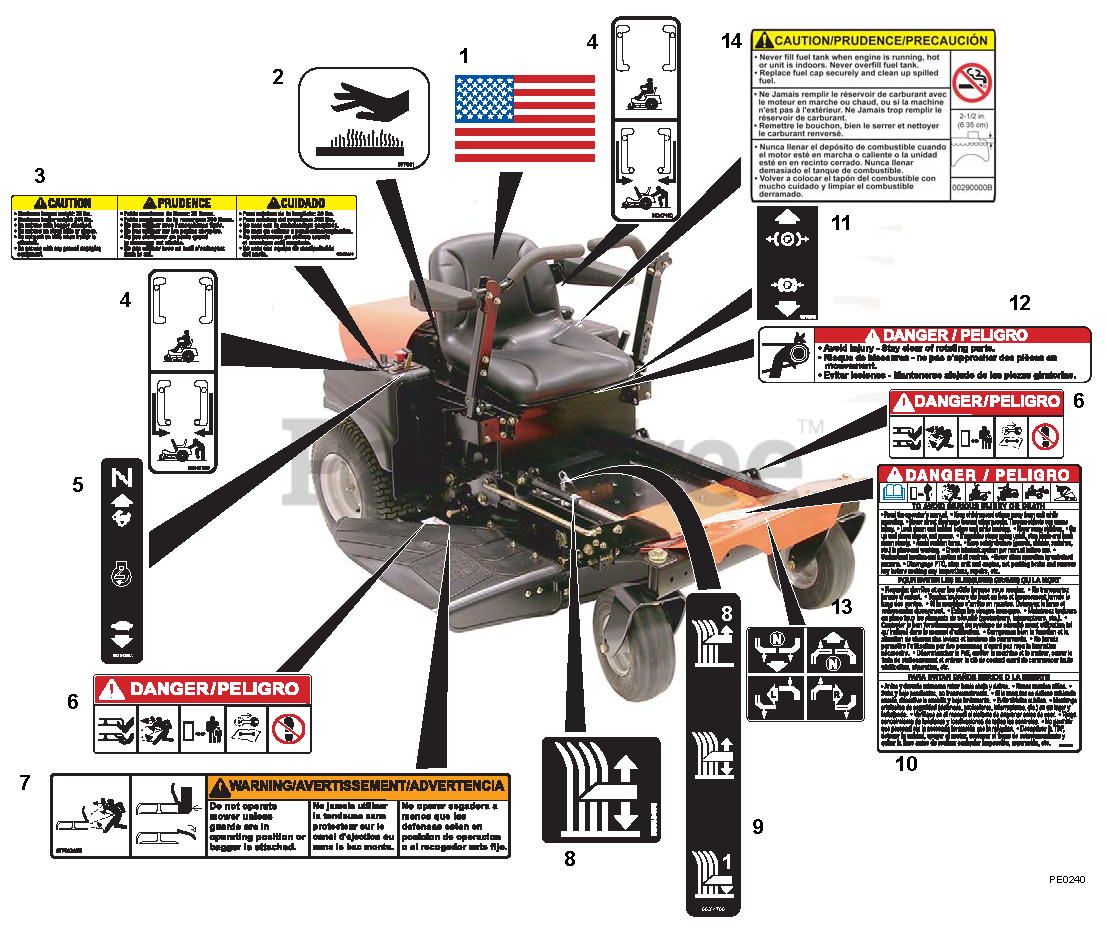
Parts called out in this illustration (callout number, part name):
1	DECAL, AMERICAN FLAG
2	DECAL, HOT SURFACE
3	DECAL, TRAILER HITCH
4	DECAL,TRANSMISSION DISCONNECT
5	DECAL-THROTTLE RER/SPORT
6	DECAL, MOWER PAN DANGER
7	DECAL, WARNING
8	DECAL-CUT HEIGHT
9	DECAL,CUT HEIGHT
10	DECAL, DANGER BILINGUAL
11	DECAL, PARKING BRAKE LEVER
12	DECAL- DANGER
13	DECAL, INSTRUCTIONAL-STEERING
14	DECAL,FUEL WARNING
